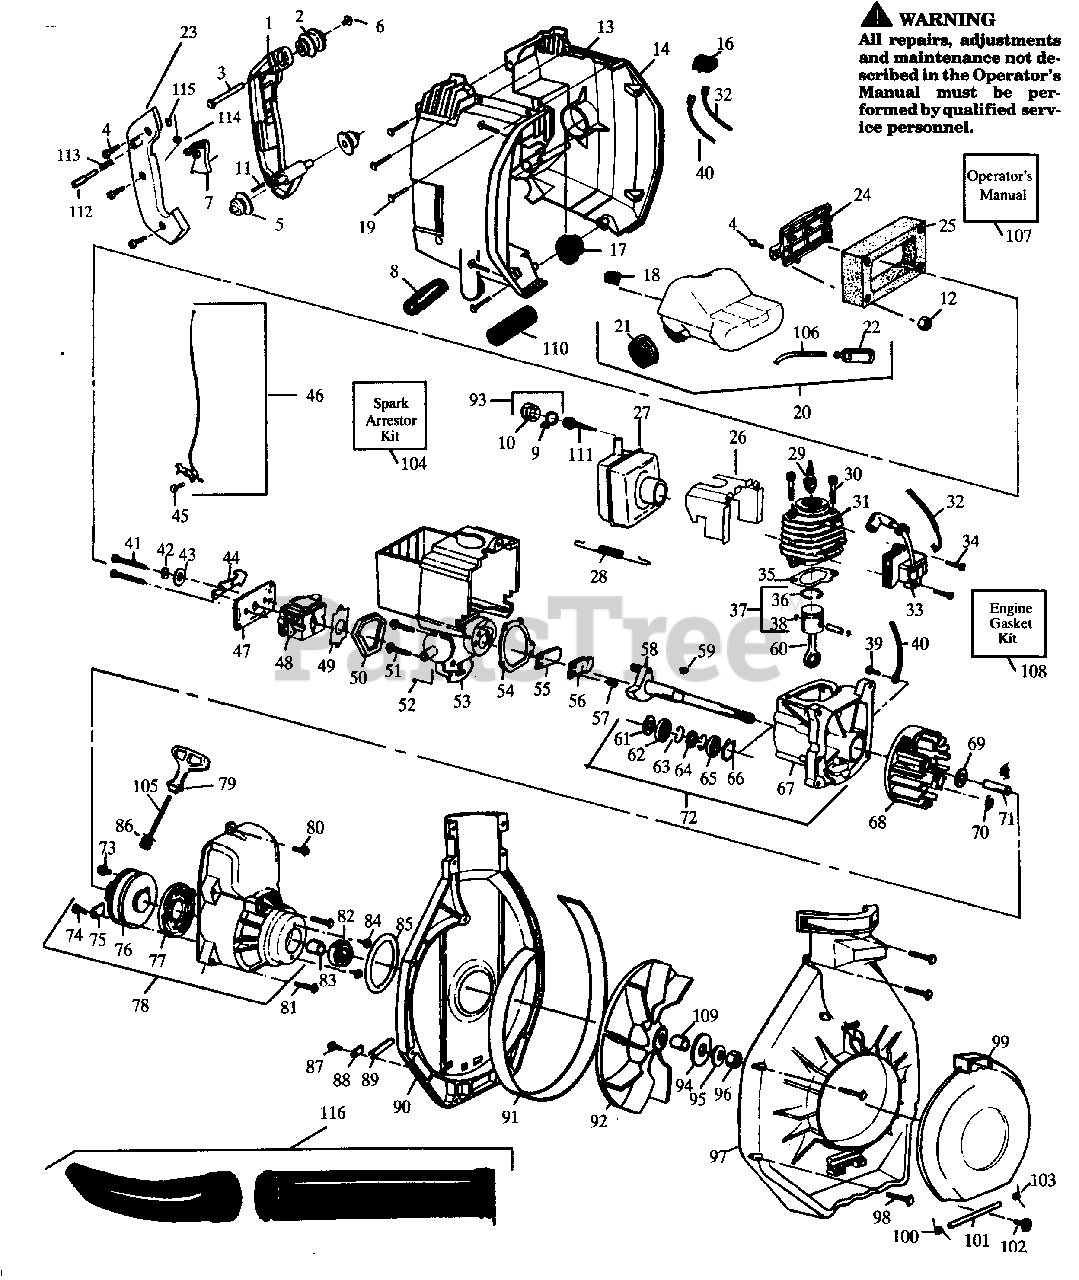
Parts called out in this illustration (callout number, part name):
1	Handle
2	Front Isolator
5	Rear Isolator
8	Assist Handle Tube
9	Spark Arrestor Clamp
10	Exhaust Deflector Ass'y.
13	Shroud-Left
14	Shroud-Right
16	Switch
17	Isolator
18	Isolator
20	Fuel Tank Ass'y.
21	Fuel Cap (w/ retainer)
22	Fuel Pick-up Ass'y.
23	Handle Cover
25	Air Filter
26	Air Baffle
29	Spark Plug (CJ-8Y)
31	Cylinder
32	Lead Wire
33	Ignition Module
35	Gasket
36	Piston Ring
37	Piston Kit
38	Retainer
40	Ground Wire
42	Wave Washer
44	Choke Shutter
46	Cable Assembly
48	Type 1 (WT-141)
48	Type 2 (WT-141A w/ Limiter Cap)
52	Ground Wire
53	Reed Block
55	Reed Valve
56	Reed Stop
58	Crankshaft-See Service Ref. 2
60	Connecting Rod Ass'y.
62	Inner Bearing
63	Retaining Ring
64	Crankshaft Seal
65	Outer Bearing
66	Retaining Ring
67	Crankcase
68	Flywheel
69	Washer
72	Crankcase/Crankshaft Assy.
75	Retainer
77	Starter Spring
78	Fan Housing Kit
79	Starter Handle
82	Bearing
84	Screw
85	"O" Ring
87	Screw
88	Retainer
89	Roll Pin
90	Blower Housing (Upper)
92	Impeller
93	Deflector & Clamp Ass'y.
97	Blower Housing (Lower)
99	Door
104	Spark Arrestor Kit
105	Rope Kit
106	Line Kit
107	Operators Manual
108	Gasket Kit
109	Hub
110	Foam Grip
111	Spark Arrestor Screen
112	Throttle Lock Button
115	"C" Clip
116	Tube and Nozzle Ass'y
